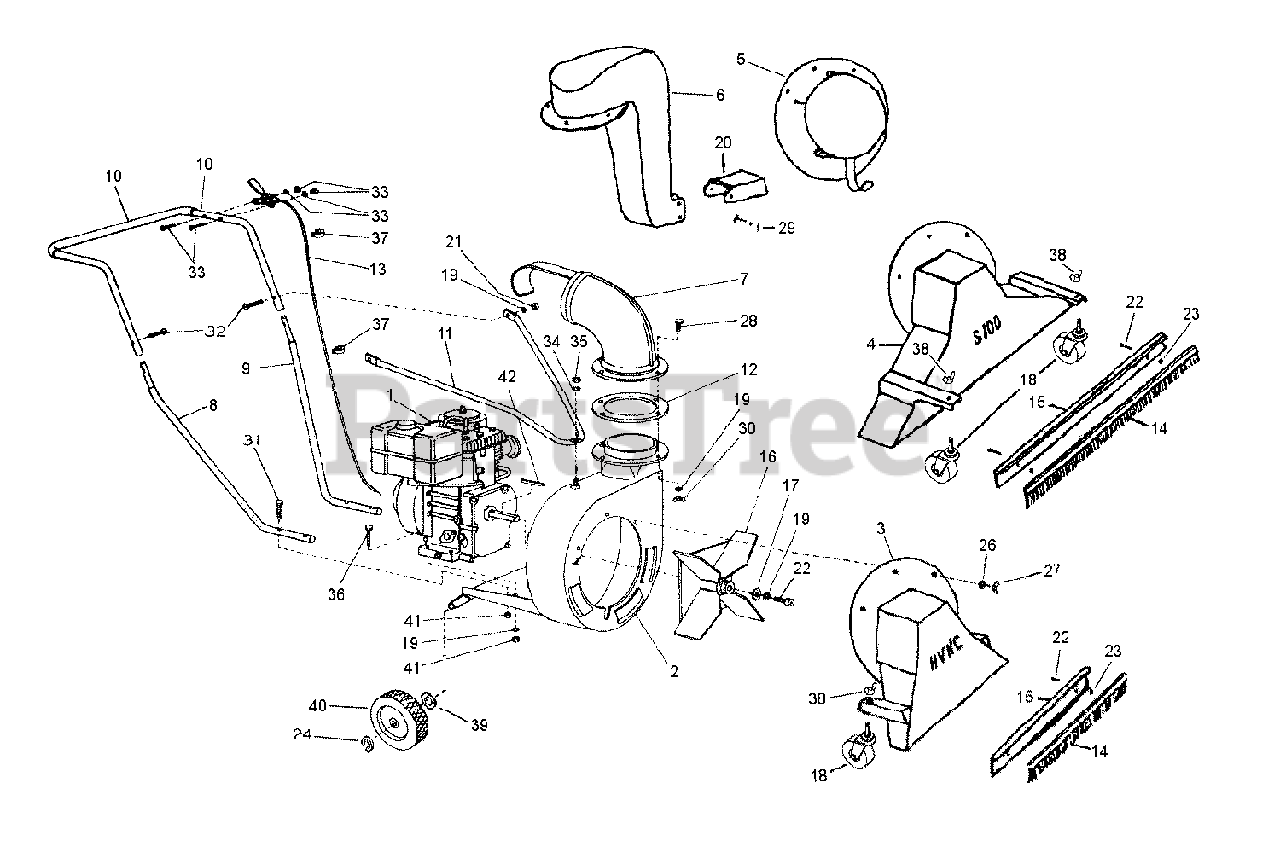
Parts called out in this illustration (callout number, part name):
1	* Engine, 9 HP B&S Intek
2	Blower housing & engine base
3	30HV nose cone body
4	S100 nose cone body
5	Intake baffle
6	Blower air chute
7	Exhaust elbow
8	Lower handle right
9	Lower handle left
10	Upper handle
10	Foam handle cover
11	Handle brace
12	Gasket, rubber
13	Throttle control
14	36" brush - S100
14	30" brush - 30HV
15	36" brush holder - S100
15	30" brush holder -30HV
16	Impeller (complete with Taper-Lok hub & hardware)
17	Hub, Taper-Lok 1-1/8"
18	Caster assembly, 4"
19	Washer, 5/16 lock
20	Blower chute deflector
21	Nut, 5/16 acorn
22	Bolt, 5/16-18 x 1-1/4 hex
23	Washer, 5/16 flat
24	Ring, Snap 5/8"
25	Kit, 3/8" lock washer and nut
26	Washer, 3/8 lock
27	Bolt, 3/8" T
28	Bolt, 5/16 x 1" hex
29	Kit, 1/4 x 5/8" bolt, lock washer and nut
30	Nut, 5/16-18 wing
31	Kit, 5/16 x 1-3/4" bolt, lock washer and nut
32	Bolt, 5/16 x 1-1/2" round slotted head
33	Kit, 10-24 x 1-1/2" bolt, lock washer and nut
34	Washer, 3/8 lock
35	Nut, 3/8’ hex
36	Bolt, 5/16-18 x 1-3/4 hex (engine mounting)
37	Throttle clip
38	Nut, 3/4" wing
39	Washer, 5/8" flat
40	Wheel Assy., 4.10/3.50-4
41	Nut, 5/16-18 hex
42	Key, Impeller, 1/4 x 2-1/8"
